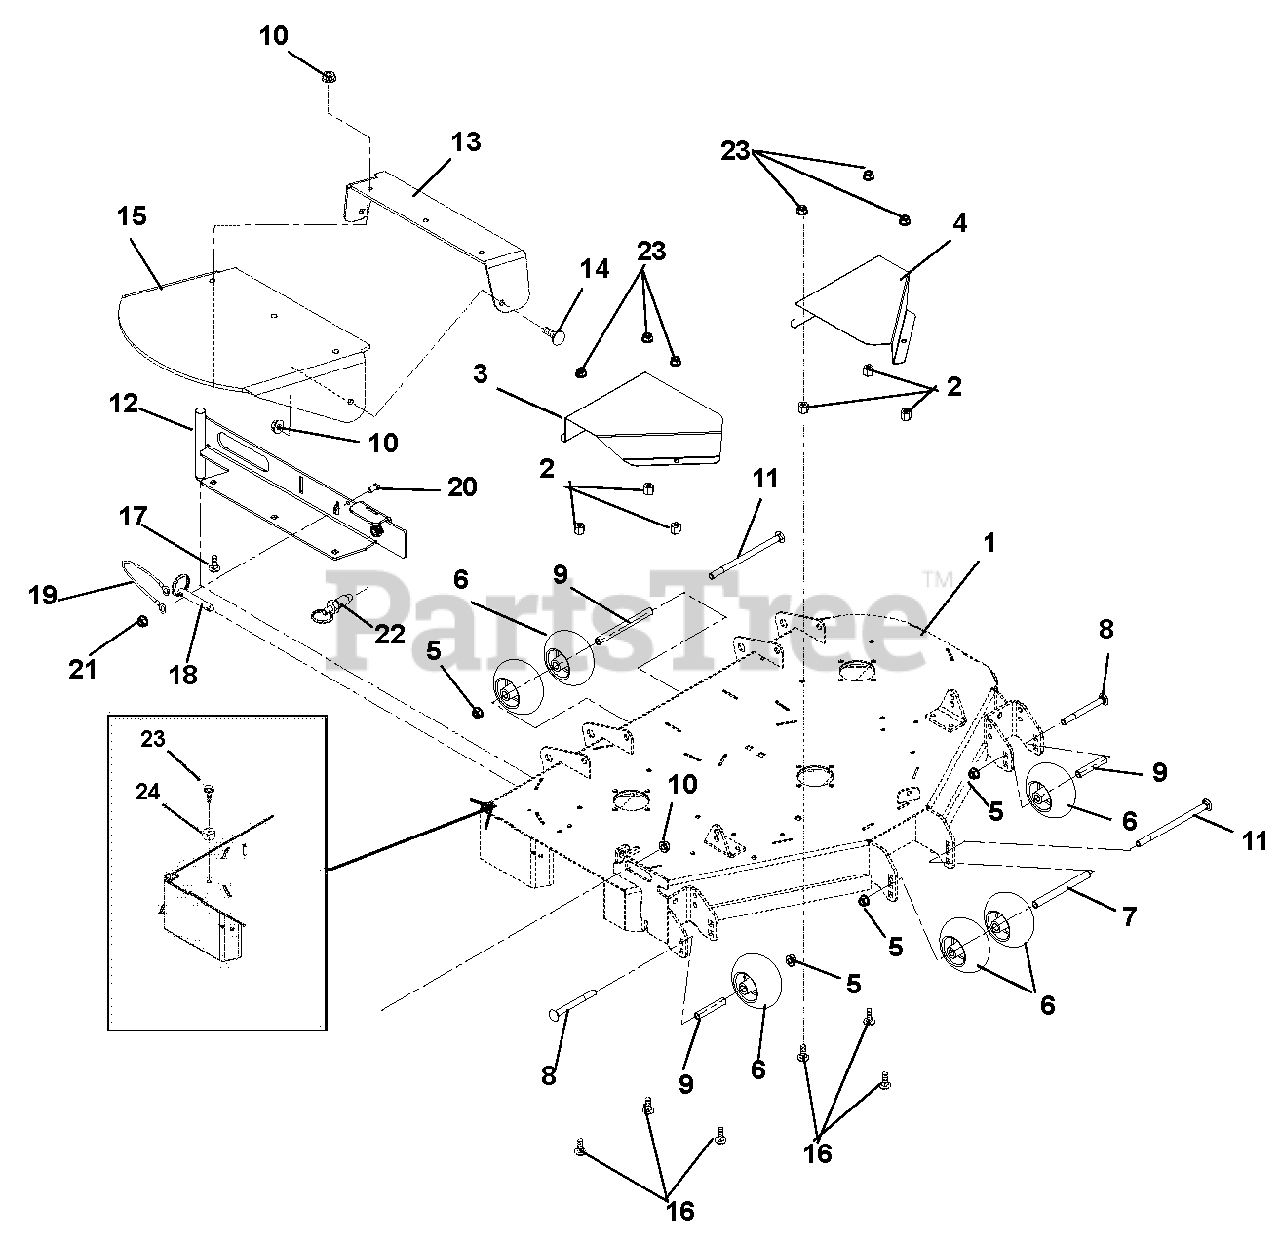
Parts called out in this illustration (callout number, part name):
1	44" Side Discharge Deck Weldment
2	Nut, Heavy Hex .38-16
3	Guard, 44-52 RH Spindle Sheave
4	Guard, 44-52 LH Spindle Sheave
5	Nut .50-13 Nyloc Flange
6	Anti-Scalp Wheel
8	Bolt, Round Head Square Neck .50-13 x 5.00
9	Spacer, .510 x .625 x 3.35
10	Nut, .38-16 Nyloc Flange
11	Bolt, Round Head Square Neck .50-13 x 8.50
12	Weldment, Discharge Chute Support
13	Rubber Discharge Chute Support
14	Bolt, Round Head Square Neck .38-16 x 1.00 Grade 5
15	Chute, Rubber Discharge
16	Bolt, Hex Head .38-16 x 1.25 Grade 5
17	Bolt, Round Head Square Neck .38-16 x 1.25 Grade 5
18	Pin, Spring Ball .375 x 1.50
19	Cable, 6.0 Lanyard
20	Bolt, Hex .25-20 x .75
21	Nut, Locking Top Flange .25-20
22	Pull Pin
23	SCREW, TAPPING .31-18 X .75 HEX WASHER HEAD THREAD
24	BUMPER, RECESSED 1.50 X .63 W/ .31
